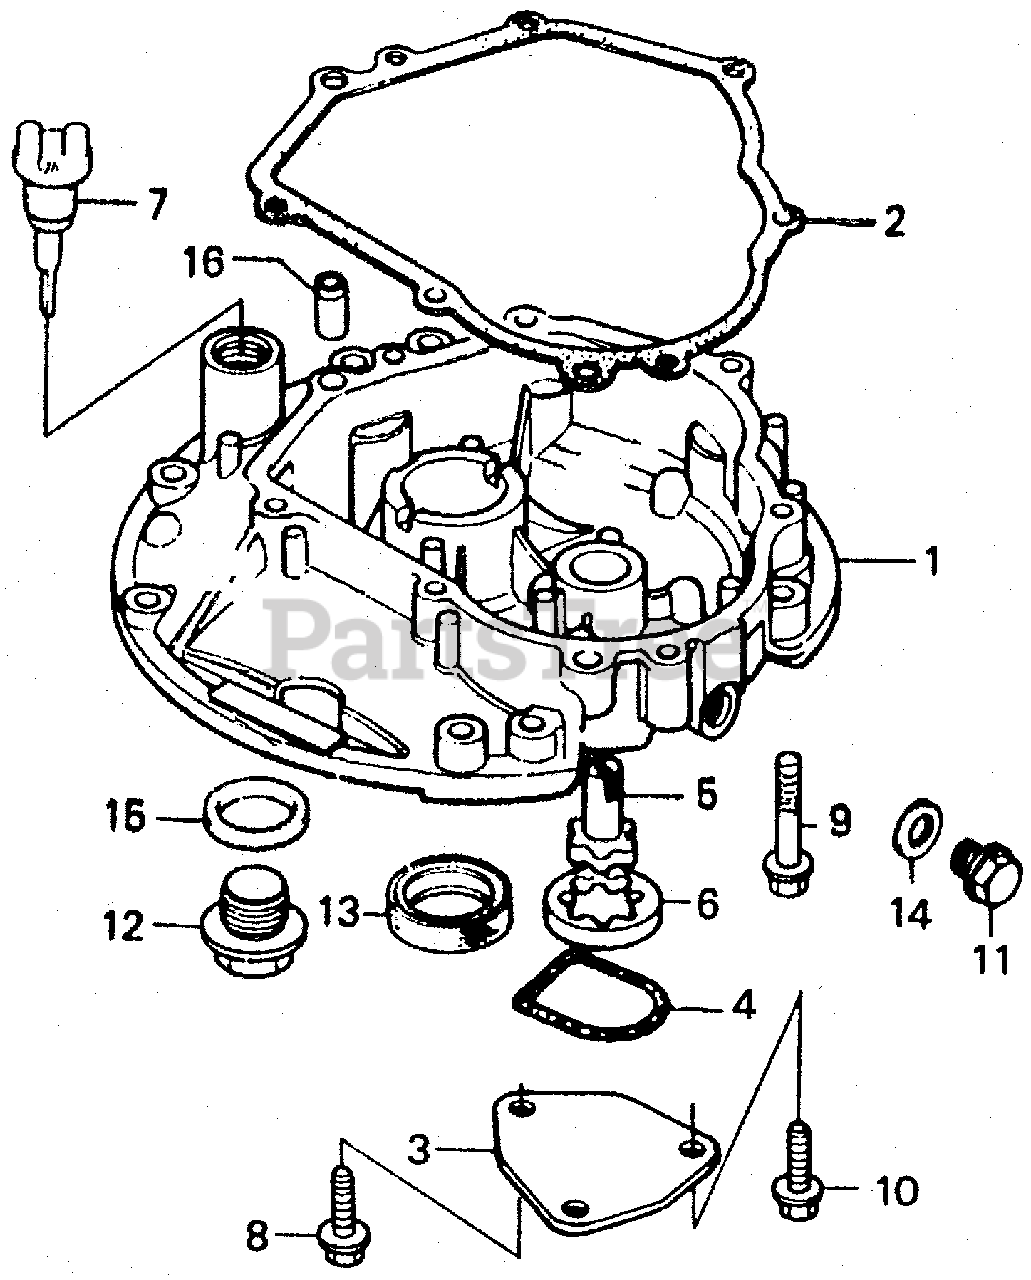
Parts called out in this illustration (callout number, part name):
1	PAN, OIL
2	GASKET, OIL PAN
3	COVER, OIL PUMP
4	O-RING, COVER
5	ROTOR (INNER)
6	ROTOR, OIL PUMP (OUTER)
7	CAP, OIL FILLER
8	BOLT, FLANGE (6X12) (CT200)
9	BOLT, FLANGE (6X32)
10	BOLT, FLANGE (6X16)
11	BOLT, DRAIN PLUG
12	BOLT, DRAIN PLUG
13	OIL SEAL (25X41X6)
14	WASHER, DRAIN PLUG (12MM)
15	WASHER, DRAIN PLUG (20MM)
16	PIN A, DOWEL (8X14)
